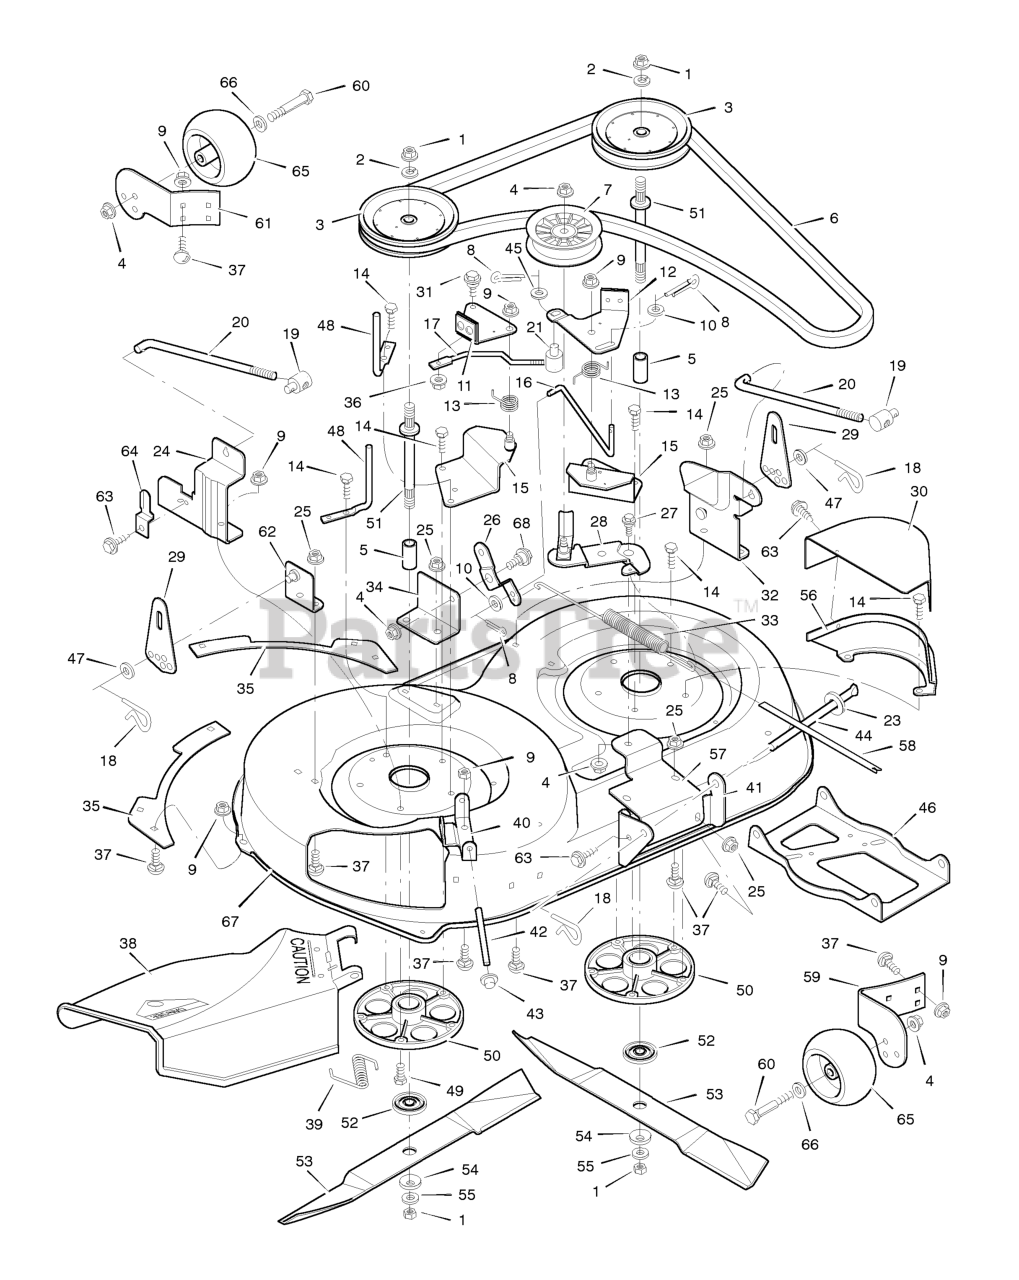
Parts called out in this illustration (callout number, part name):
1	Nut, Hex
2	Lockwasher
3	Pulley, Jackshaft
4	Locknut, Flange
6	Belt, Blade Drive
7	Pulley, Idler
8	Pin, Cotter
9	Locknut, Flange
11	Brake Assembly, Right
12	Brake Assembly, Left
13	Spring, Torsion
14	Bolt, Hex
15	Bracket Assembly, Brake
16	Rod, Brake
17	Rod, Cross Link
18	Pin, Hair
19	NUT, Adjusting, 1/2-13
20	Rod, Adjuster
21	Nut, Adjustable
24	Bracket, Right
25	Nut, Flange
26	Bracket, Pivot
27	Bolt, Shoulder
28	Arm Assembly, Idler
29	Plate, Adjuster
30	Cover, Pulley
31	Bolt, Shoulder
32	Bracket Assembly, Left Lifter
33	Spring, Extension
34	Bracket, Pivot
36	Locknut, Flange
37	Bolt, Carriage
38	Deflector Assembly, Chute
39	Spring, Torsion
40	Bracket, Hinge
41	Bracket, Front Hanger
42	Rod, Deflector
43	Cap, Push On
44	Rod, Hanger
46	Hanger, Front
48	Rod, Belt Guide
49	Bolt, Hex
50	Housing, Jackshaft
51	Jackshaft
52	Adapter, Blade
53	Blade, 42" (2 required)
54	Washer, Belleville
56	Bracket, Pulley Cover
57	Bracket, Idler Mount
58	Indicator, Plastic
59	Bracket, Right Wheel
60	BOLT, Gauge Wheel
61	Bracket, Left Wheel
62	Bracket Assembly, Right Lifter
64	Guide, Belt
65	Wheel, Gauge
66	Washer
67	Housing, Blade
68	Bolt, Shoulder
